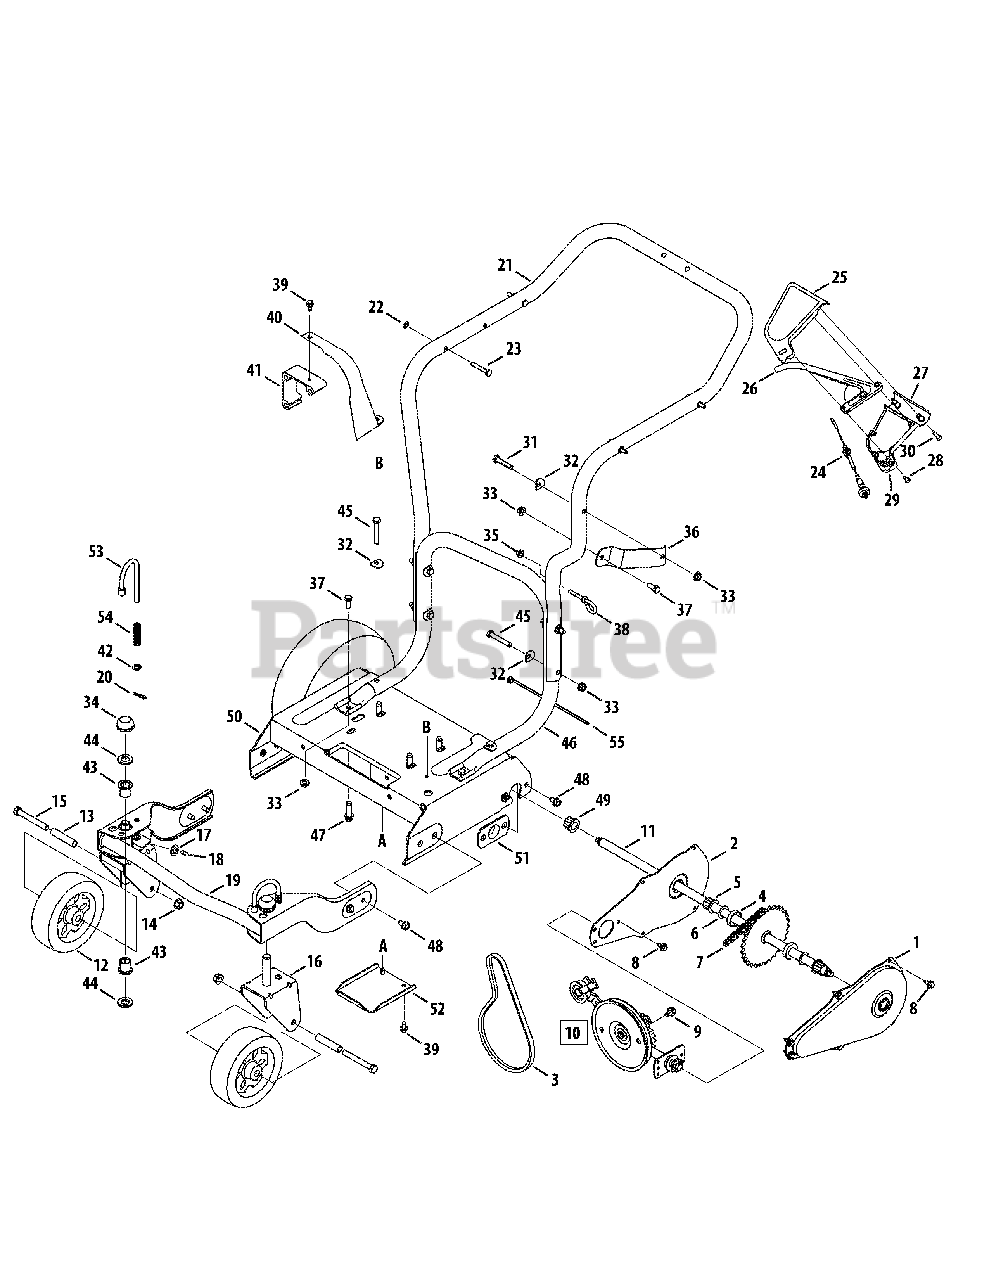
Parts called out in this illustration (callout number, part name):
3	V-Belt
5	Hex Flange Bearing
6	Flat Washer
7	Chain
8	TT Screw, 1/4-14 x 0.625"
9	Hex Washer Screw, 5/16
10	Chipper Shredder Trans. Ass’y.
11	Axle Assembly
12	Wheel, 6.0 x 2.0
14	Flange Lock Nut, 3/8-16
15	Hex Cap Screw, 3/8-16 x 3.0
17	Flat Washer, .203 ID x.403 OD
18	Grease Fitting, 3/16
20	Cotter Pin
23	Stud Pin, .250 x 1.75
24	Clutch Cable - 56"
25	Upper Clutch Cover
26	Drive Lever
27	Lower Clutch Cover
28	Screw, #10-12 x.750
29	Mounting Cable Cap
30	Screw, #10-16 x 1.25
31	Hex Cap Screw, 5/16-18 x 1.50
32	Shoulder Washer, .320 ID x.93 OD
33	Hex Flange Lock Nut, 5/16-18
35	Hex Nut, 1/4-28
37	Hex Cap Screw, 5/16-18 x.75
39	Hex Washer Screw, 1/4-14 x.625
40	Belt Cover
41	Engine Mounting Adapter
42	Flat Washer, .330 ID x.630 OD
43	Flange Bearing, .632 ID
44	Flat Washer, 5/8 ID x 1.0 OD
45	Hex Cap Screw, 5/16-18 x 1.75
47	Screw, 3/8-16 x 1.25
48	Hex Washer Screw, 5/16-18 x.625
49	Hex Flange Bearing, .631 x.720
54	Compression Spring
55	Cable Tie
